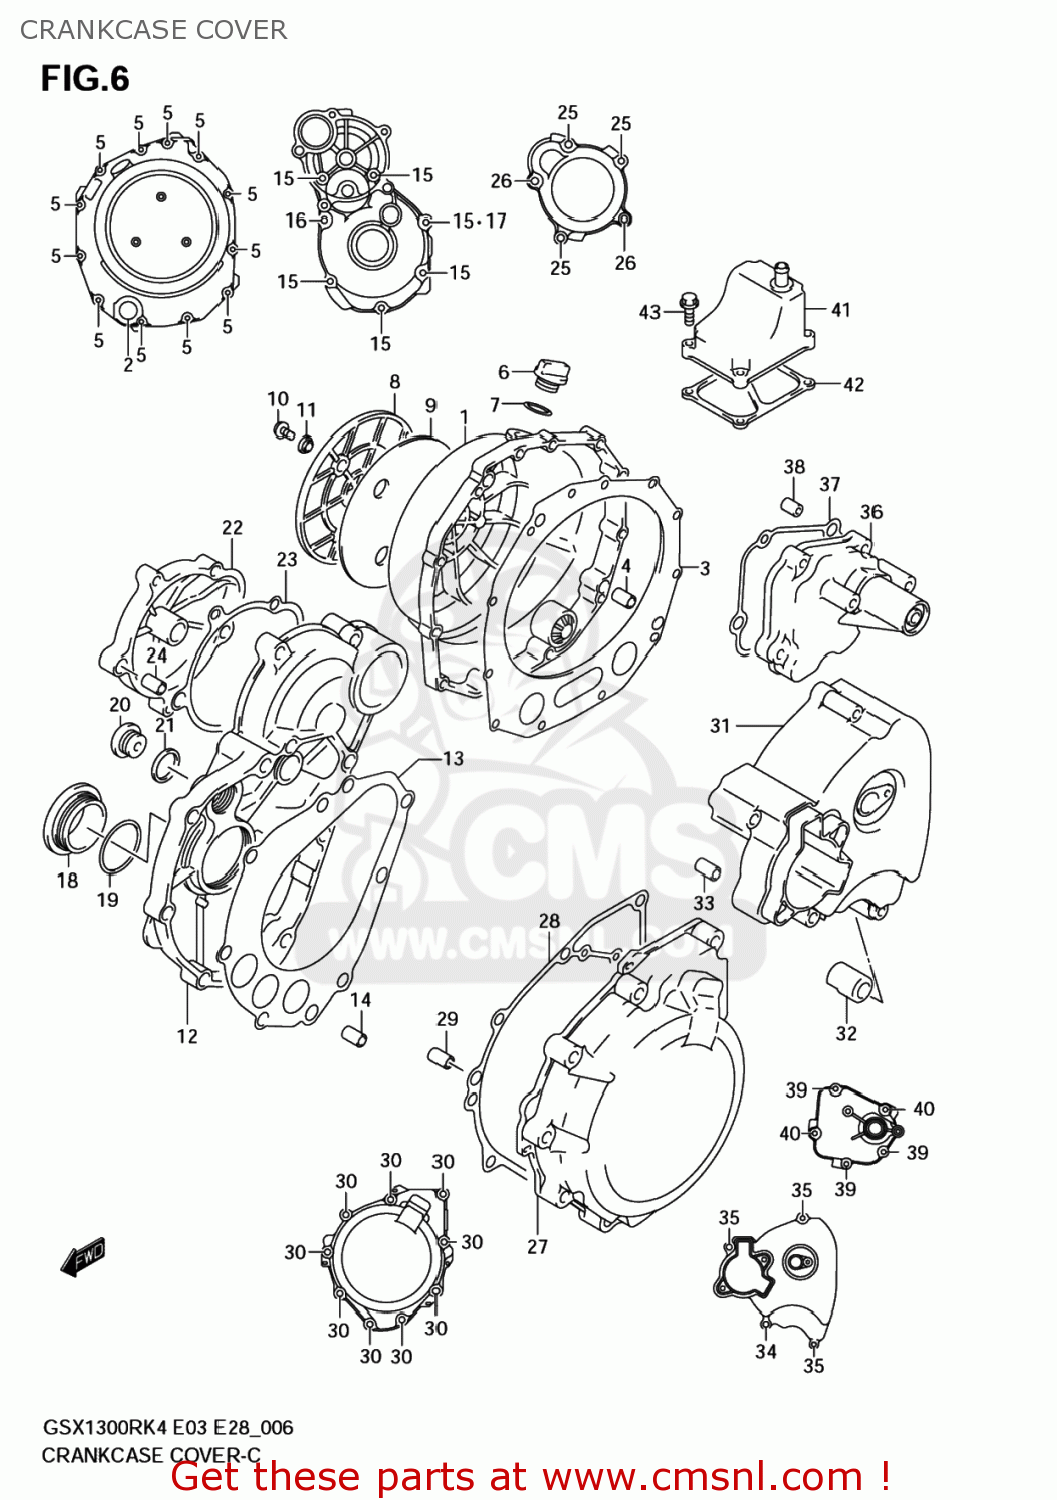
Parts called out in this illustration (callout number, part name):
1	COVER,CLUTCH
2	LENS,OIL LEVEL CHECK
3	GASKET,CL COVER (NAS)
4	PIN
5	BOLT(6X30)
6	PLUG,ENGINE OIL FILLER
7	O RING(D:3.1,ID:16.8)
8	COVER,CLUTCH OUTER
9	CUSHION,CLUTCH OUTER COVER
10	SCREW(6X16)
11	WASHER,CLUTCH OUTER COV SCREW
12	COVER,STARTER CLUTCH
13	GASKET,STARTER CLUTCH COVER (NAS)
14	PIN
15	BOLT(6X25)
16	BOLT(6X35)
17	GASKET(5.8X13X1.2) (NAS)
18	PLUG
19	O RING(D:3.1,ID:32.7)
20	PLUG,16X8
21	GASKET(16X22X2) (NAS)
22	CAP,STARTER IDLE GEAR
23	GASKET,START IDLE GEAR CAP (NAS)
24	PIN
25	BOLT(6X25)
26	BOLT(6X35)
27	COVER,MAGNETO
28	GASKET,MAGNETO COVER (NAS)
29	PIN
30	BOLT(6X30)
31	COVER,ENGINE SPROCKET
32	PROTECTOR,ENGINE SPRKT COVER
33	PIN
34	BOLT(6X40)
35	BOLT(6X55)
36	COVER,GEAR SHIFT
37	GASKET,GEAR SHIFT COVER (NAS)
38	PIN
39	SCREW
40	BOLT
41	COVER,BREATHER
42	GASKET,BREATHER COVER (NAS)
43	BOLT,G/S SWITC
